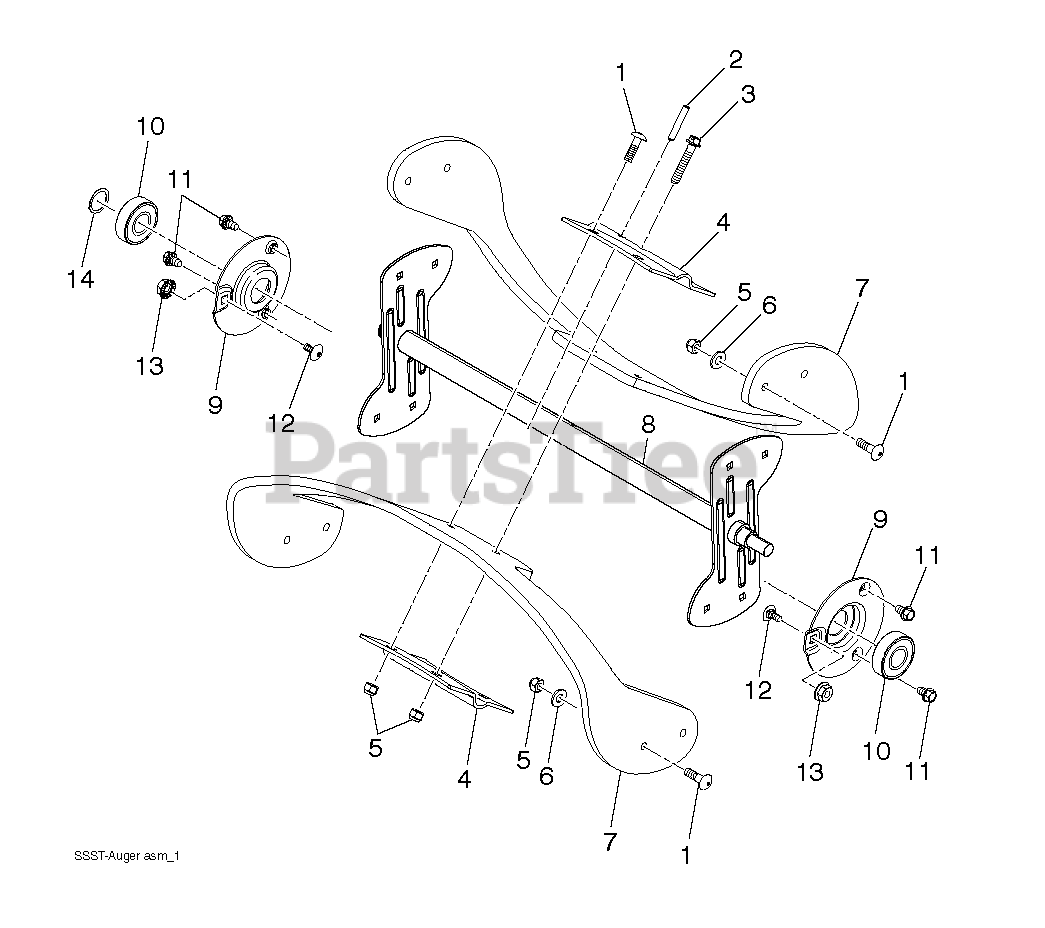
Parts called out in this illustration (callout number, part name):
1	BOLT.CARRIAGE.1/4-20 X 7/8
2	PIN.ROLL.3/16 X 1-1/4
4	PLATE.CENTER.BLADE
5	NUT
7	AUGER.BLADE.SS.SNOW
8	WELDMENT.AUGER.SINGLE.STAGE.BL
9	SUPPORT.BEARING.SSST.
10	BEARING.BALL.MANDREL
11	SCREW 1/4X20
13	NUT.FLANGE.1-4-20-SERR
14	RETAINING RING LT
